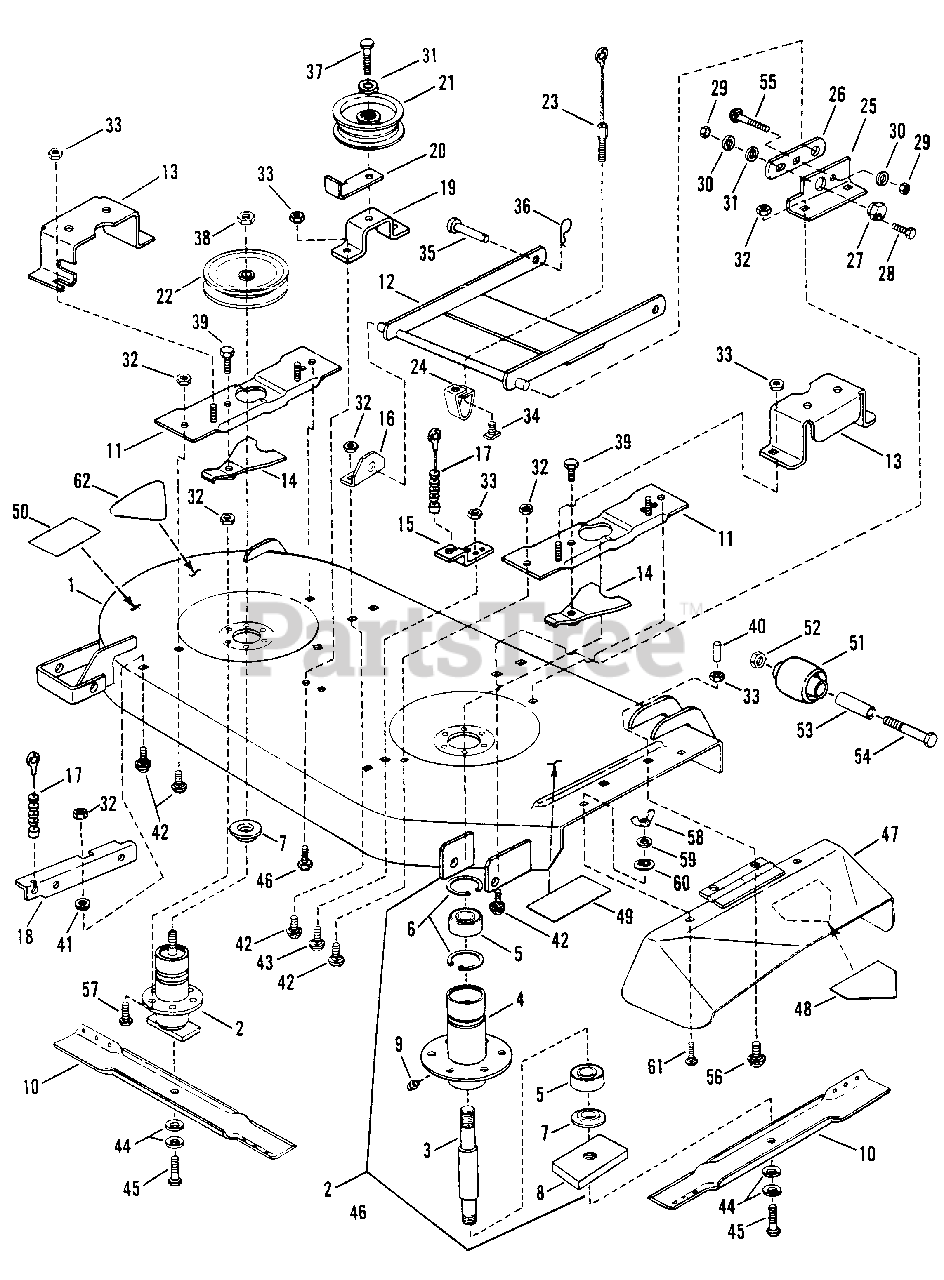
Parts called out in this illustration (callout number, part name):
1	DECK, Mower, 41"
2	ASSEMBLY, Spindle
3	SPINDLE 6.5" Long
4	HOUSING, Spindle 5.1" Tall
5	BEARING, Spindle
6	RING, Retaining EXT 1.75"
7	WASHER, Spindle
8	HOLDER, Blade
9	FITTING, Lube (Press into .187" hole, no ball)
10	BLADE, 21" Cutter
11	ASSEMBLY, Rear Support
12	ASSEMBLY, Front Hanger
13	GUARD, Pulley
14	ASSEMBLY, Spindle Lock
15	ASSEMBLY, Chain Support
16	BRACKET, Front Left Hanger
17	CABLE, Support (4.25", 8 Spacers)
18	ASSEMBLY, Rear Support
19	BRACKET, Idler Mount
20	GUIDE, Belt
21	PULLEY, Flat Idler 4.12" OD
22	PULLEY, Spindle "V" 5.75" OD .750" ID Hole
23	CABLE, Front Lift 6.12"
24	BRACKET, Front Lift Arm Hanger
25	BRACKET, Front Right
26	LINK, Adjustment
27	RING, Adjustment
28	SCREW, 3/8-16 x 1" Hex Head Cap
29	NUT, 3/8-16 Hex
30	WASHER, 3/8" Split Lock
31	WASHER. 3/8 Flat
32	NUT, 3/8-16 Hex Flange Lock
33	NUT, 5/16-18 Hex Flange Lock
34	T-NUT, 5/16-18
35	PIN, 1/2 x 1 3/8" Clevis
36	HAIRPIN, Cotter
37	SCREW, 3/8-16 x 1 1/2" Hex Cap
38	NUT, 3/4-16 Hex Jam
39	BOLT, 3/8-16 x 1" Hex Flange Lock
40	CAP, Vinyl
41	WASHER. 7/16 Flat
42	BOLT, 3/8-16 x 3/4" Carriage
43	BOLT, 5/16-18 x 3/4" Carriage
44	WASHER, 13/32 x 1 13/32" Dia., Cone
45	SCREW, 3/8-24 x 1 1/4" Hex Cap
46	BOLT, 5/16-18 x 3/4" Hex Flange Lock
47	DEFLECTOR, Side Chute
48	DECAL, Danger
49	DECAL, Caution (Deflector in Place)
50	DECAL, Caution (Rotating Blades)
51	WHEEL, Gage
52	LOCKNUT, 3/8-24 Hex
53	SPACER
54	SCREW, 3/8-24 x 3 3/4" Hex Head Cap
55	BOLT, 3/8-16 x 3/4" Short Neck Carriage
56	BOLT, 5/16-18 x 1" Short Neck Carriage
57	BOLT, 3/8-16 x 3/4" Hex Flange Lock
58	WING-NUT, 5/16-18
59	WASHER, 5/16 Split Lock
60	RETAINER, 5/16 Bolt
61	BOLT, 5/16-18 x 5/8" Carriage
62	DECAL, 42"
